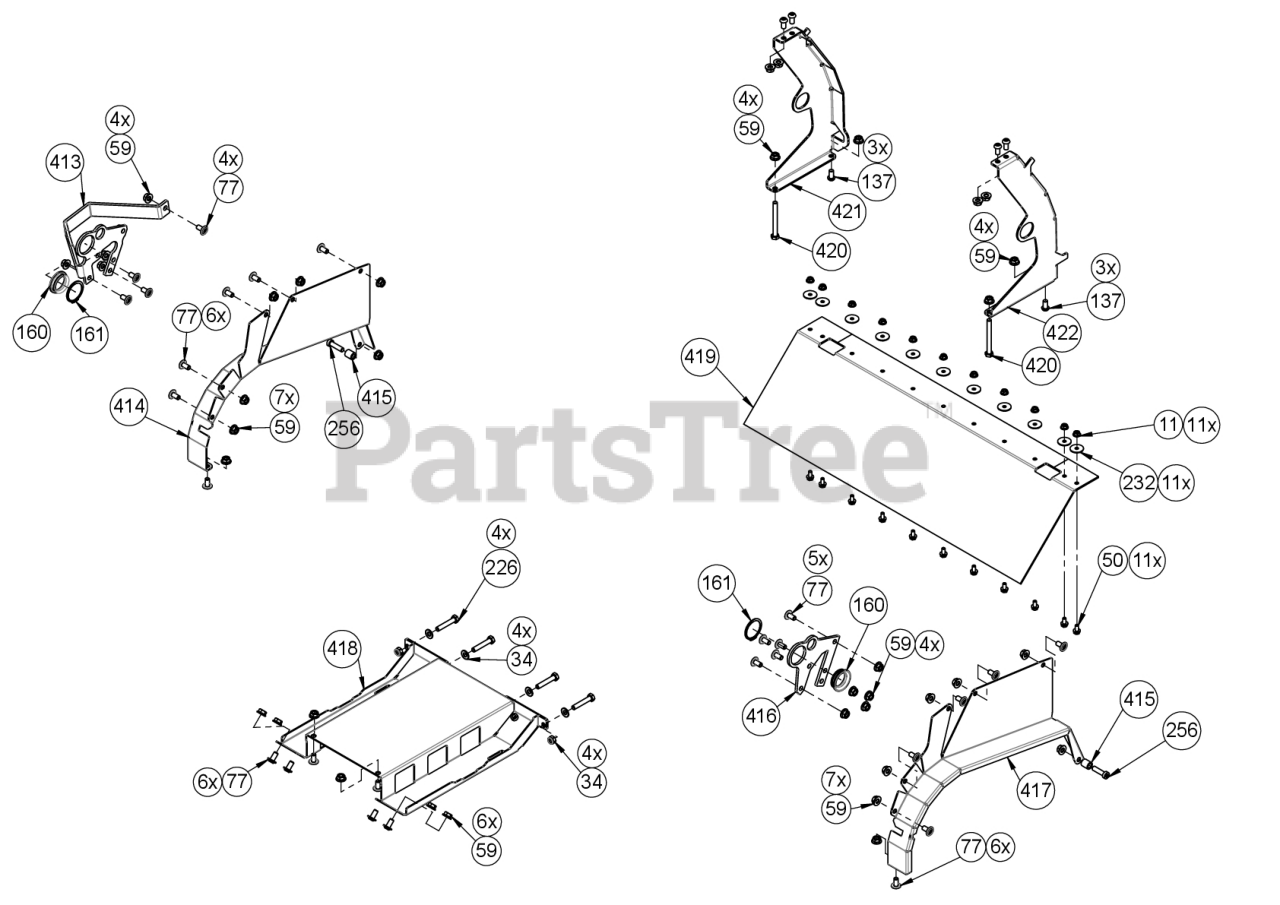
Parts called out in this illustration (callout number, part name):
11	NUT, FLG SLF LK M6 CL 8 ZCC
34	NUT, LK-NYL M8 DIN 985 8 ZCC
50	BLT, FLG SLF LK M6X12
59	NUT, FLG SLF LK M8 CL 8 ZCC
77	TORX FBHCS M8X16-8.8
137	TORX BHCS M8X16 8.8
161	RG-RTNG-EXT M38 DIN 471
226	BLT, HEX M8X 45 DIN 931 8.8 ZCC
232	WSHR, FLT M6.4XM25X1.5
256	TORX SHCS M8X30 8.8
413	INTENA GUARD
414	FENDER, LEFT
416	PLATE, HOLDING
417	FENDER, RIGHT
418	PLATE, BOTTOM
419	DISCHARGE CHUTE
420	BLT, HEX M8X75 DIN 931 8.8 ZCC
421	BRKT, LH GUIDE
422	BRKT, RH GUIDE
